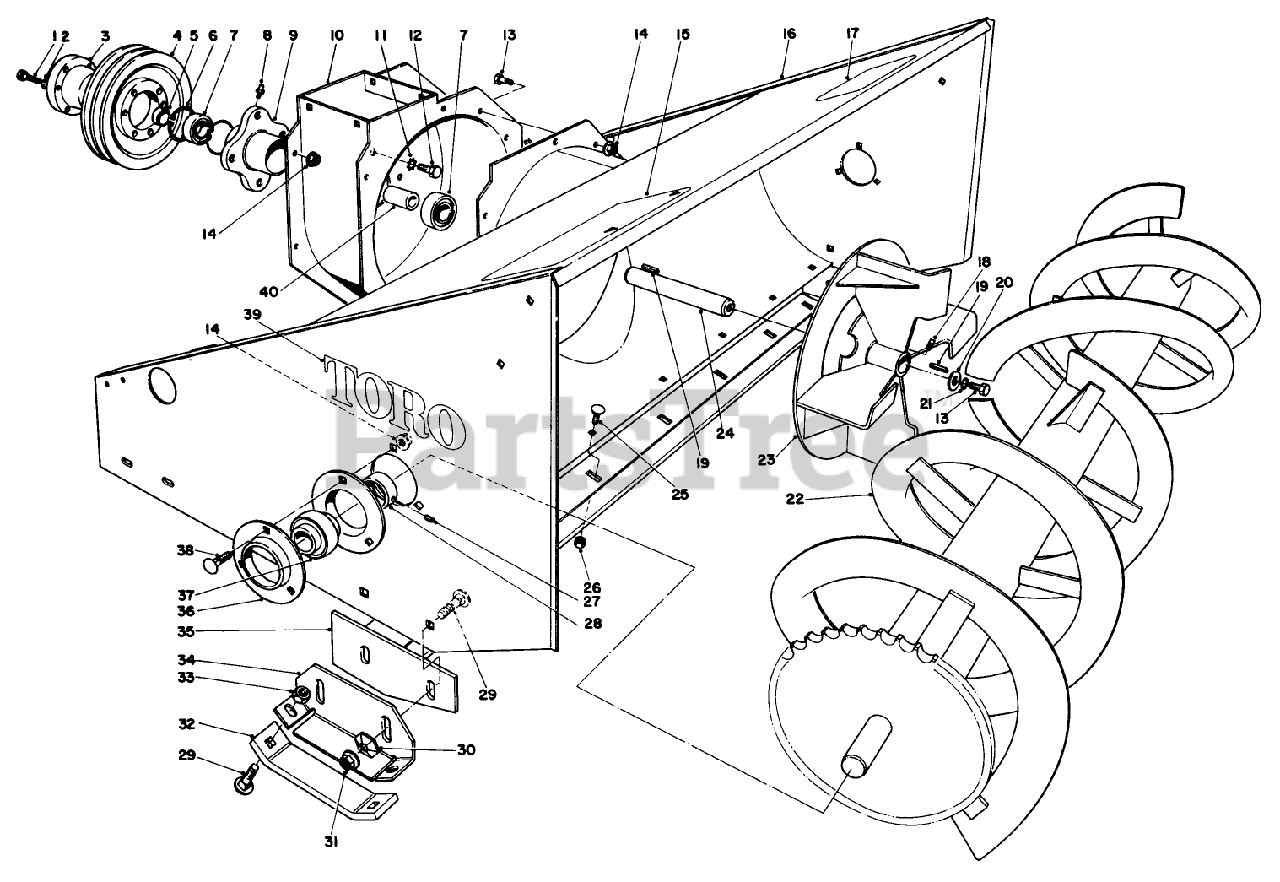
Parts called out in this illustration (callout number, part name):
1	SCREW-HH
2	SCREW-HH
7	BEARING
8	FITTING-LUBE, 45 DEG
11	WASHER-LOCK, EXT
12	SCREW-HH
13	SCREW-HH
14	NUT-HF
18	SCREW-HH
20	WASHER
21	SCREW-HH
25	BOLT-CARR
26	NUT-LOCK, NI
27	SCREW-SET, HSH
28	COLLAR-LOCK, BEARING
29	SCREW-HH
30	LOCKWASHER-PYRAMID
33	NUT-LOCK, CONE
37	BEARING
38	SCREW-CARR
